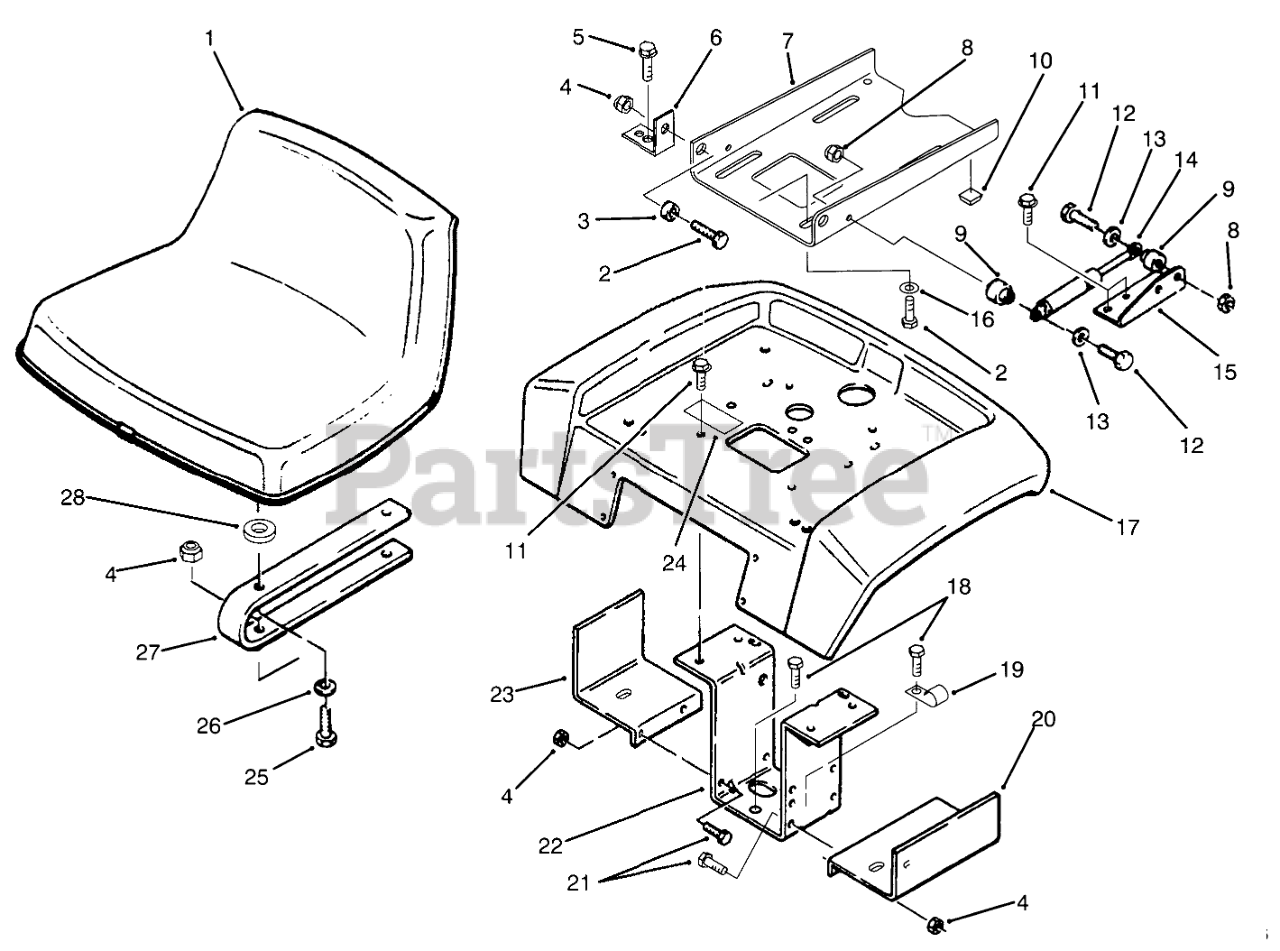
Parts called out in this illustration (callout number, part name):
1	SEAT V-510
2	SCREW-HH
3	BUSHING
4	NUT-LOCK, NI
5	Bolt
6	BRACKET-PIVOT
7	Plate-SeatPivot
8	NUT-LOCK, NI
9	SPACER
10	BUMPER SJ5514 BLACK
11	SCREW
12	SCREW-HH
13	WASHER-FLAT
14	GAS SPRING
15	BRACKET-CYLINDER R
16	WASHER-PLAIN
17	Fender
18	SCREW-HH, LOCK
19	CLIP
20	Fuel Tank Support LH
21	SCREW-HH
22	Bracket-Fender
23	Support-FueITank RH
24	DECAL-DO NOT TOW
25	SCREW-HH
26	WASHER-LOCK
27	Seat Spring
28	SPACER-NYLON
